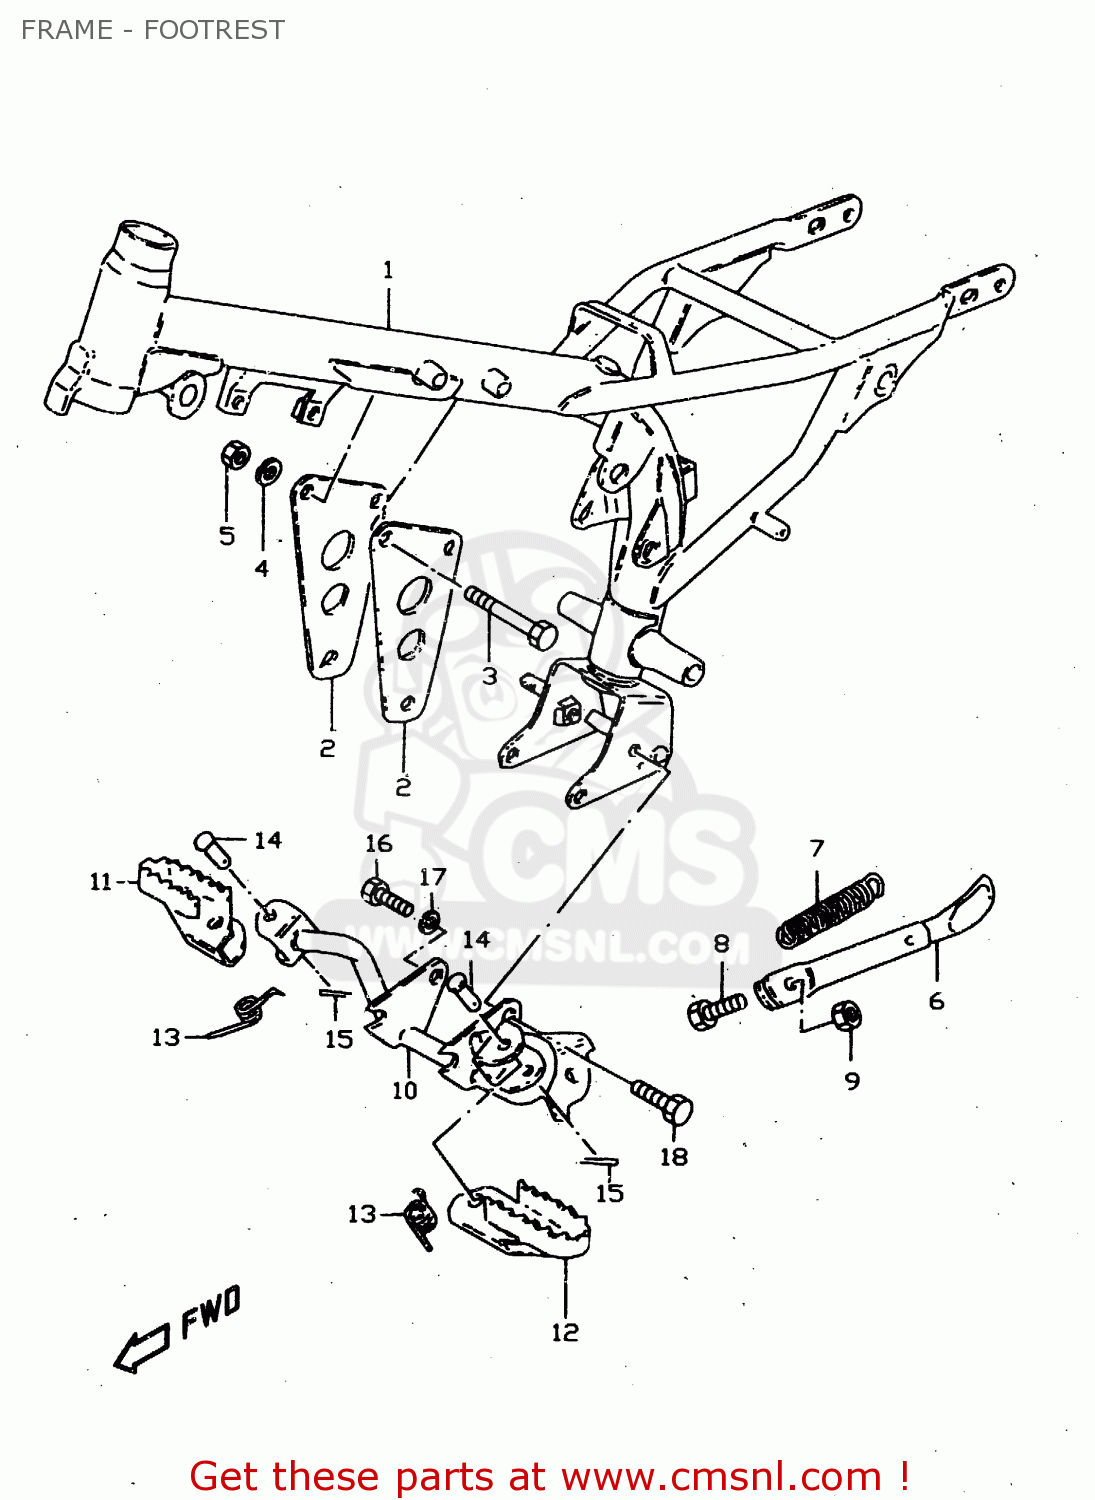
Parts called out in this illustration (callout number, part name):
1	FRAME (BLACK)
2	PLATE,ENG MTG
3	BOLT
4	LOCK WASHER
5	NUT
6	STAND,PROP
7	SPRING
8	BOLT 8X22
9	NUT
10	BAR,FR FOOTREST
11	FOOTREST,FR,R
12	FOOTREST,FR,L
13	SPRING
14	PIN
15	PIN
16	BOLT
17	LOCK WASHER
18	BOLT(8X14)
